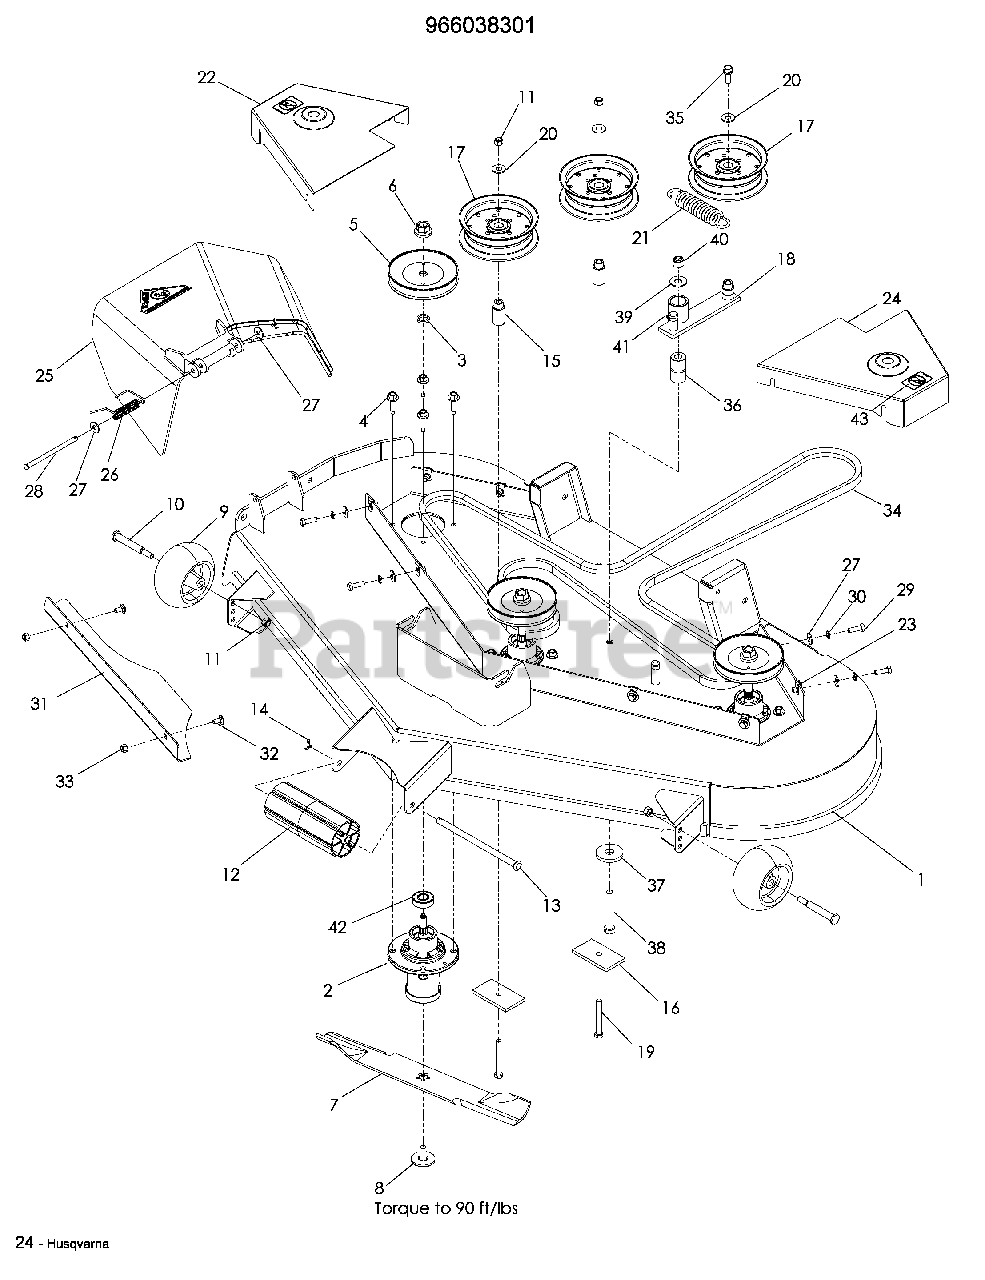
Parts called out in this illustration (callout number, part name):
1	DECK w/DECALS
2	HOUSING ASSM
3	WASHER, SPACER
4	SCREW 5/16 -18 x WSH HD
5	PULLEY
6	NUT 9/16 TOP CNTRLK
7	BLADE, 18"
8	BOLT 7/16 BLADE
9	WHEEL, GAUGE
10	BOLT ½-16 x 25/8 SHOULDER
11	NUT 3/8-16 HEX NYLOC
12	ROLLER, NOSE
13	ROD, ROLLER, NOSE
14	PIN, COTTER 1/8 x ¾
15	BUSHING, IDLER
16	PAD, PAINTED
17	PULLEY, IDLER
18	ARM, IDLER
19	HCS 3/8-16 x 3
20	WASHER 3/8 FLAT STD
22	BELT SHIELD, RT
23	RETAINER, U TYPE
24	BELT SHIELD, LT
25	CHUTE, DISCHARGE
26	SPRING, TORSION
27	WASHER 5/16 STD FLAT
28	PIN, CLEVIS 5/16
29	HCS 5/16-18 x 1
30	WASHER 5/16 SLW
31	PLATE, CONFINEMENT
32	RHSNB 5/16-18 x 5/8
33	NUT 5/16-18 HEX NYLOC
35	HCS 3/8-16 x 1 WHIZLK
36	BUSHING, PIVOT
37	WASHER, SUPPORT
38	HCS ½-13 x 3¼
39	WASHER ½ STD FLAT
40	NUT ½ HEX NYLOC
41	ZERK
42	BEARING, BALL
43	DECAL, NO STEP
